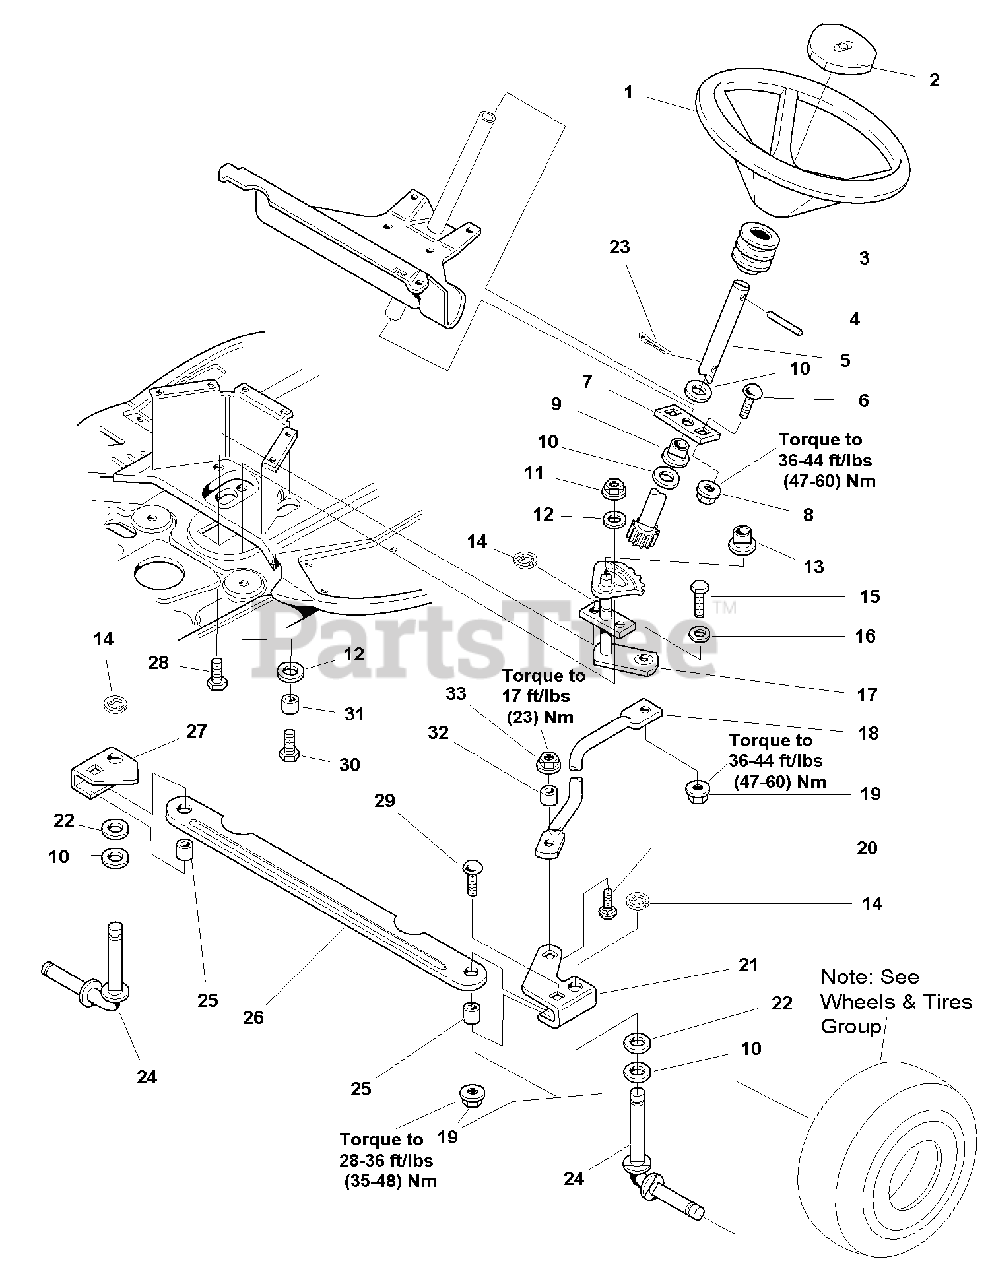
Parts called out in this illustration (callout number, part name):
1	STEERING WHEEL
2	CAP, Steering Wheel, Simplicity
3	TUBE, Cover
4	PIN, Spring
5	SHAFT & PINION ASSEMBLY
6	CARRIAGE BOLT, 3/8-16 x 1
7	PLATE, Mounting
8	NUT, Hex Whiz Lock, 3/8-16
9	BUSHING, 3/4, Nylon
10	WASHER, 3/4
11	NUT, Hex Lock, 5/16-18
12	WASHER, 5/16
13	BUSHING, 3/4, Powered Metal
14	RING, Klipring Extension
15	CAPSCREW, Hex Head, 3/8-16 x 1-1/4
16	WASHER, 3/8
17	SHAFT & GEAR ASSEMBLY
18	LINK, 19.66" Long
19	NUT, Hex Flange Lock, 3/8-16
20	CARRIAGE BOLT, 5/16-18 x 1
21	ARM & SPACER ASSEMBLY, LH Splined
22	WASHER, 3/4
23	PIN, Cotter
24	SPINDLE & CUP ASSEMBLY
27	ARM & SPACER ASSEMBLY, RH Splined
28	CAPSCREW, Hex Head Taptite, 5/16-18 x 3/4
29	CARRIAGE BOLT, 3/8-16 x 1-1/4
30	CAPSCREW, Hex Head, 5/16-18 x 1-1/2
33	NUT, Hex Flange Lock, 5/16-18
